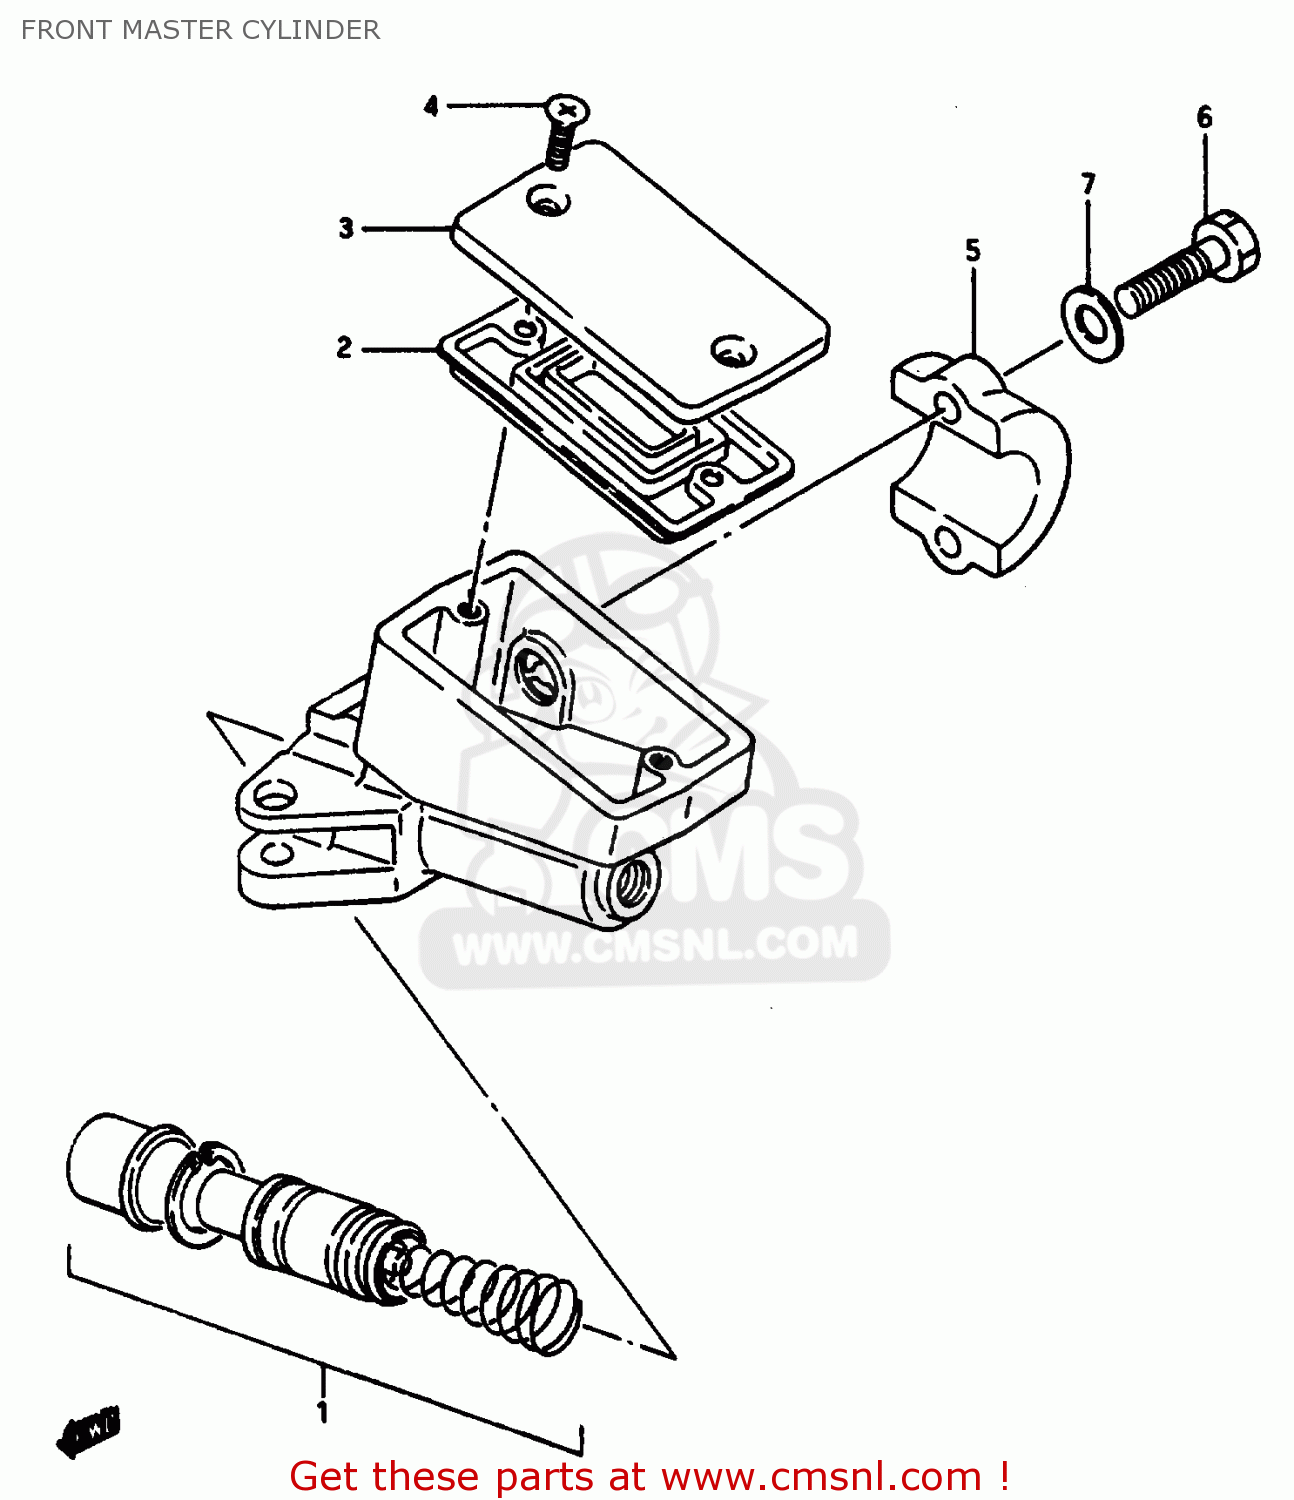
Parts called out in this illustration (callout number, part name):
1	PISTON & CUP SET
2	3
3	CAP
4	SCREW
5	HOLDER,MASTER CYLINDER
6	BOLT
7	WASHER
